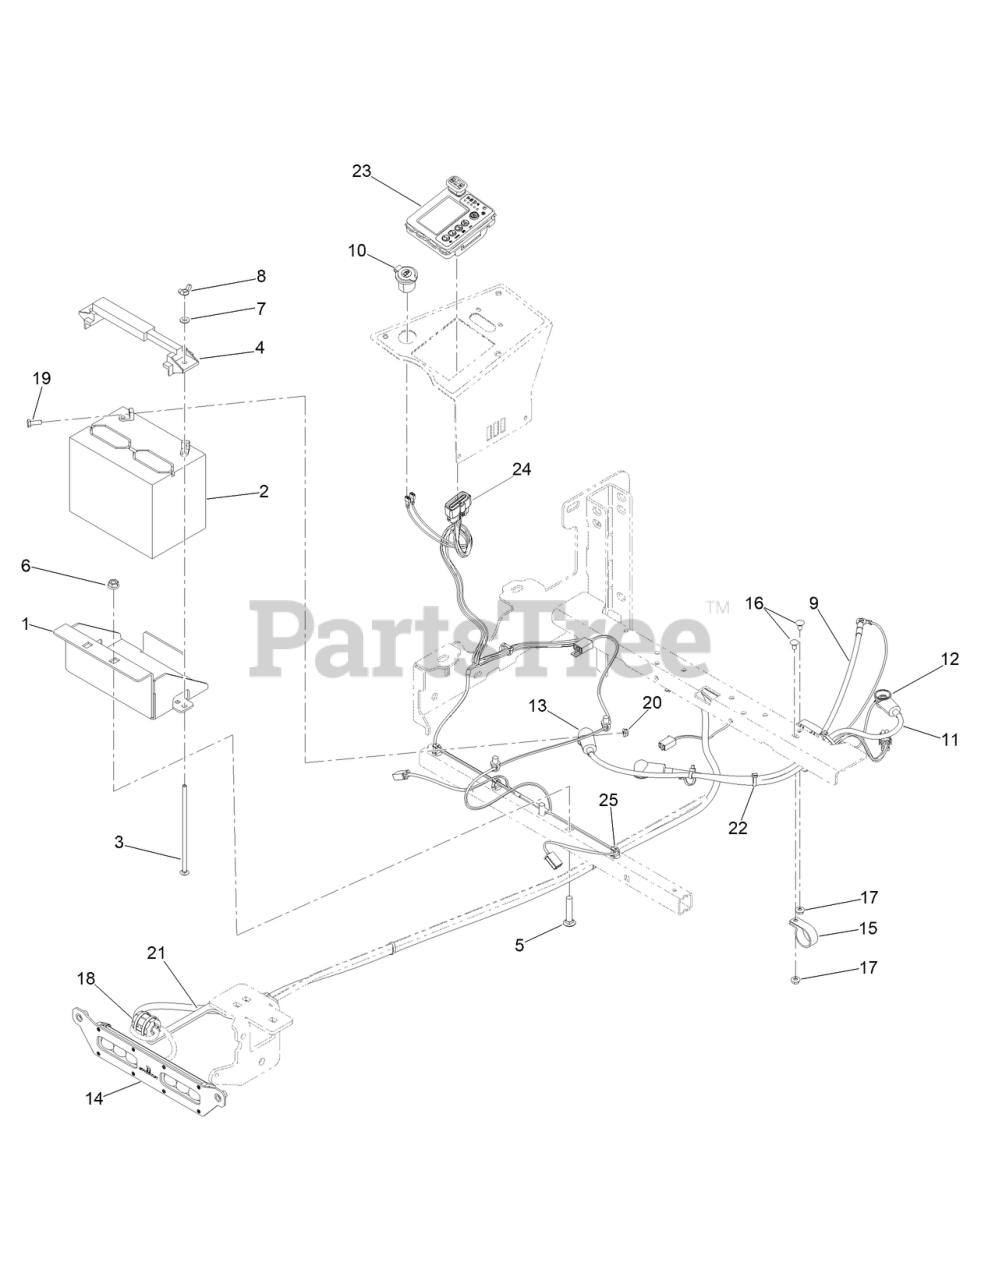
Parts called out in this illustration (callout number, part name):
1	MWR BATTERY BOX BLACK
2	12 VOLT START BATTERY 300CCA
3	1/4-20 X 7 CARRIAGE BOLT ZINC
4	BATTERY HOLD DOWN
5	SCREW-CARR
6	3/8-16 HEX FLANGE NUT W/SERR ZINC YELLOW
7	WASHER-FLAT
8	NUT-WING
9	MWR NEGATIVE CABLE 28
10	12 VOLT AUXILLIARY PLUG
11	MWR POSITIVE BATTERY CABLE 25IN
12	3.15 LGTH STRAIGHT INSUL TERM COVER RED
13	STRAIGHT INSULATING TERMINAL COVER
14	SPLIT BEAM W/NON-LIGHTD HELMET LIGHT BAR
15	1-1/4IN CUSHIONED LOOP CLAMP BLACK
16	SCREW-CARR
17	1/4-20 HEX FLANGE NUT
18	FAIR-RITE ROUND CABLE SNAP-IT SIZE B
19	SCREW-HH
20	NUT-HF
21	FAIR-RITE BRACKET PAINTED
22	TIE-CABLE
23	CONSOLE-VG ADVANCE
24	HARNESS-WIRE
25	CLIP-TIE
